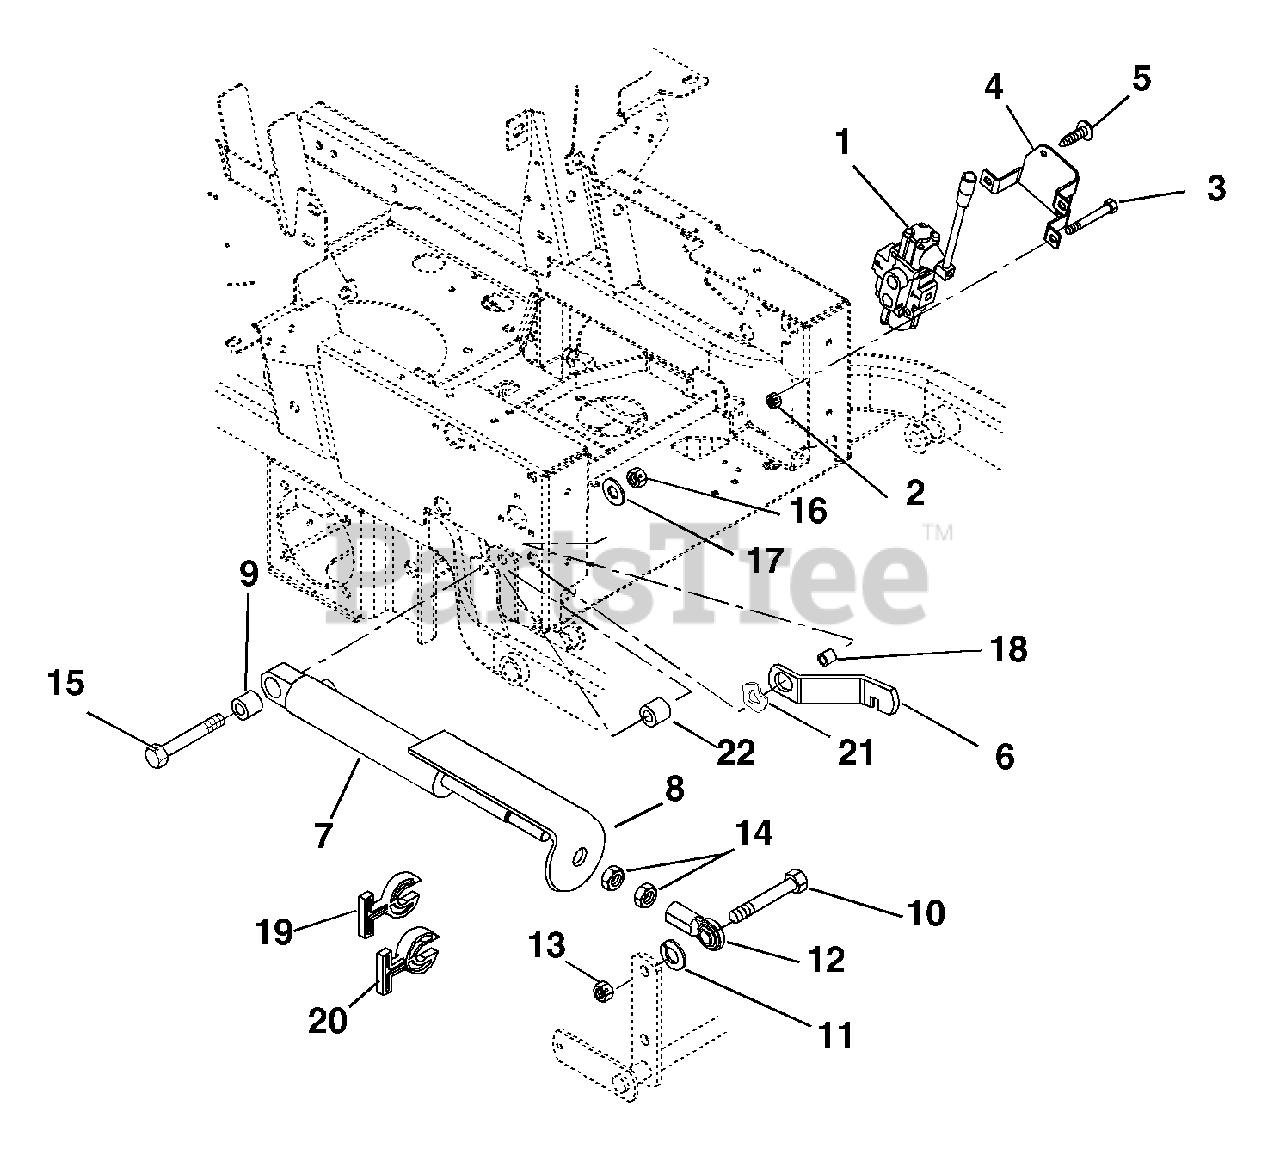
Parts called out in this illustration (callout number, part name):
1	Valve, Hydraulic
2	Nut-Locking-Top-Flange .31-18
3	Bolt-Hex .31-18 x 2.25 Grade 5
4	Valve Mounting Bracket
5	Screw-Tapping .38-16 x .50 Hex Washer Head
7	Cylinder-Hydraulic Lift
8	Strap, Cut Indicator/Guard
9	Bushing .516 x 1.000 x 1.050
10	Bolt-Hex .62-11 x 2.25 Grade 8
11	Washer-Lock .62 x .156
12	Rod End-Right Hand-Female 5/8
13	Nut-Locking-Center .62-11
14	Nut-Jam .625-18
15	Post, Cylinder Stop
16	Nut-Locking-Top-Flange .50-13
17	Washer-Flat-Steel .515 x 1.625 x .25
18	Bushing-Flange .515 x .75 x .275 x 1.12
19	Stop, Cylinder .34 Thick
20	Stop, Cylinder .68 Thick
21	Washer-Wave .076 x 1.12 xz .08
22	Bushing .50 x .875 x .875
